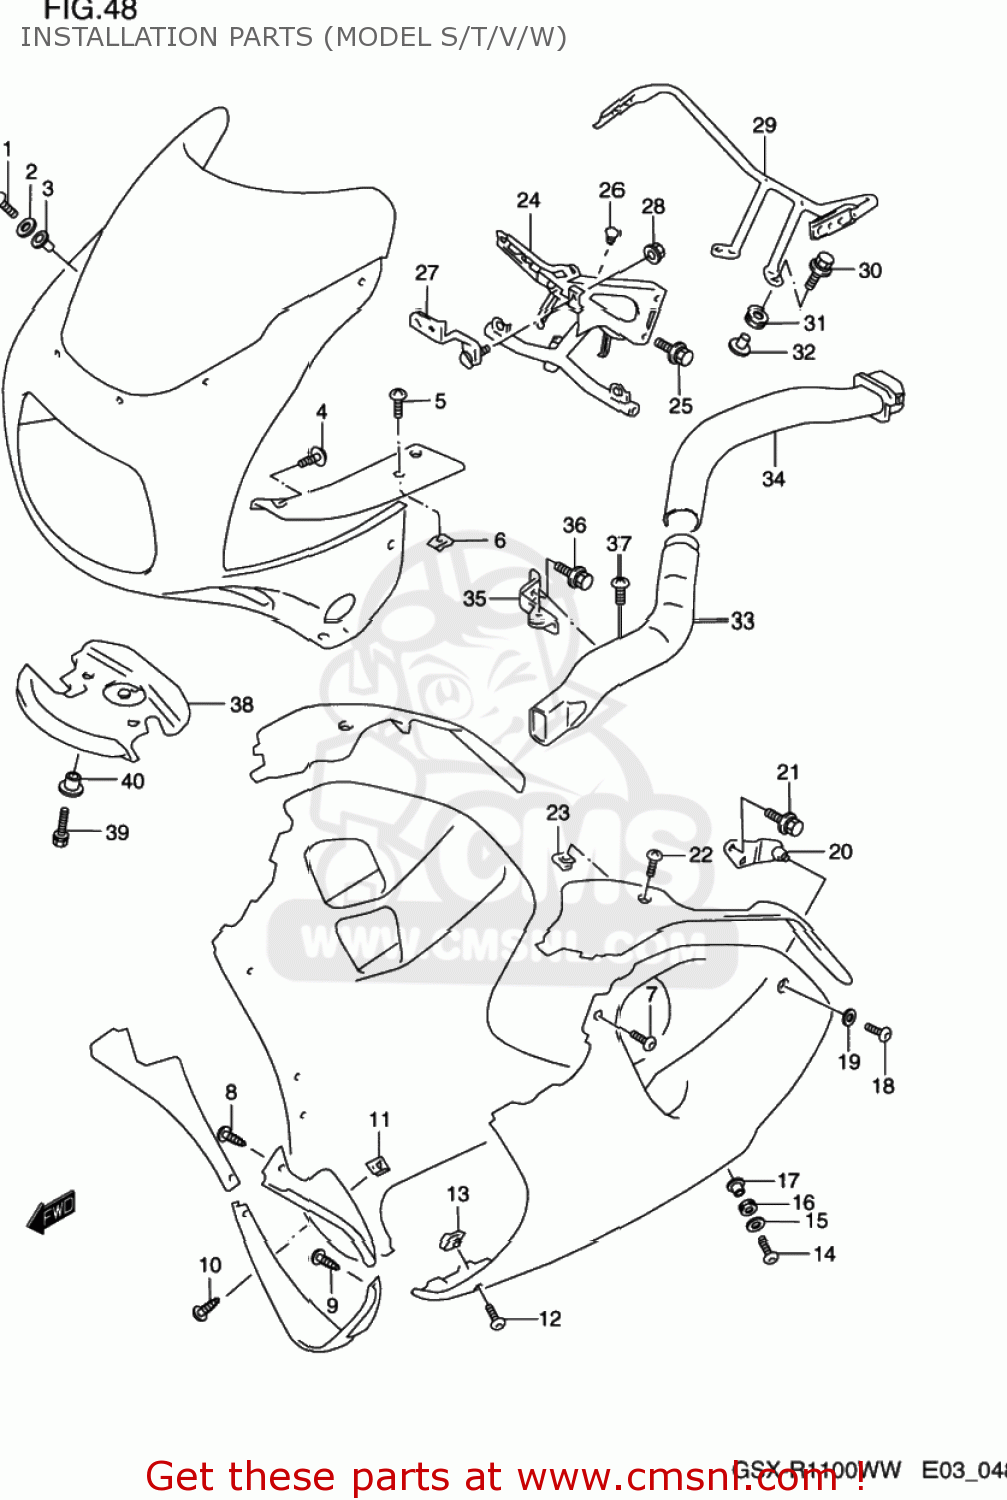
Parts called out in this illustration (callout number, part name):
1	SCREW(5X14)
2	WASHER
3	NUT
4	SCREW 5X10
5	SCREW L:12
6	NUT
7	SCREW(5X16)
8	SCREW 5X10
9	SCREW 5X10
10	SCREW(5X16)
11	NUT,HEADLAMP HOUSING,UPPER
12	SCREW(5X16)
13	NUT,HEADLAMP HOUSING,UPPER
14	SCREW(6X25)
15	WASHER(6.5X18X1)
16	CUSHION
17	WASHER
18	SCREW(6X10)
19	WASHER
20	BRACKET,UNDER COWLING UPR,R
21	BOLT
22	SCREW L:12
23	NUT
24	BRACE,COWLING
25	BOLT
26	CAP(OD:14)
27	BRACKET,HEADLAMP
28	NUT
29	BRACE,RR VIEW MIRRORR
30	BOLT(6X25)
31	CUSHION
32	WASHER,MIRROR BRACE,IN
33	PIPE,AIR INTAKE FR,L
34	PIPE,AIR INTAKE RR
35	BRACKET,AIR INTAKE,LEFT
36	BOLT
37	SCREW 6X12
38	COVER,COWLING FR LWR
39	BOLT
40	WASHER
